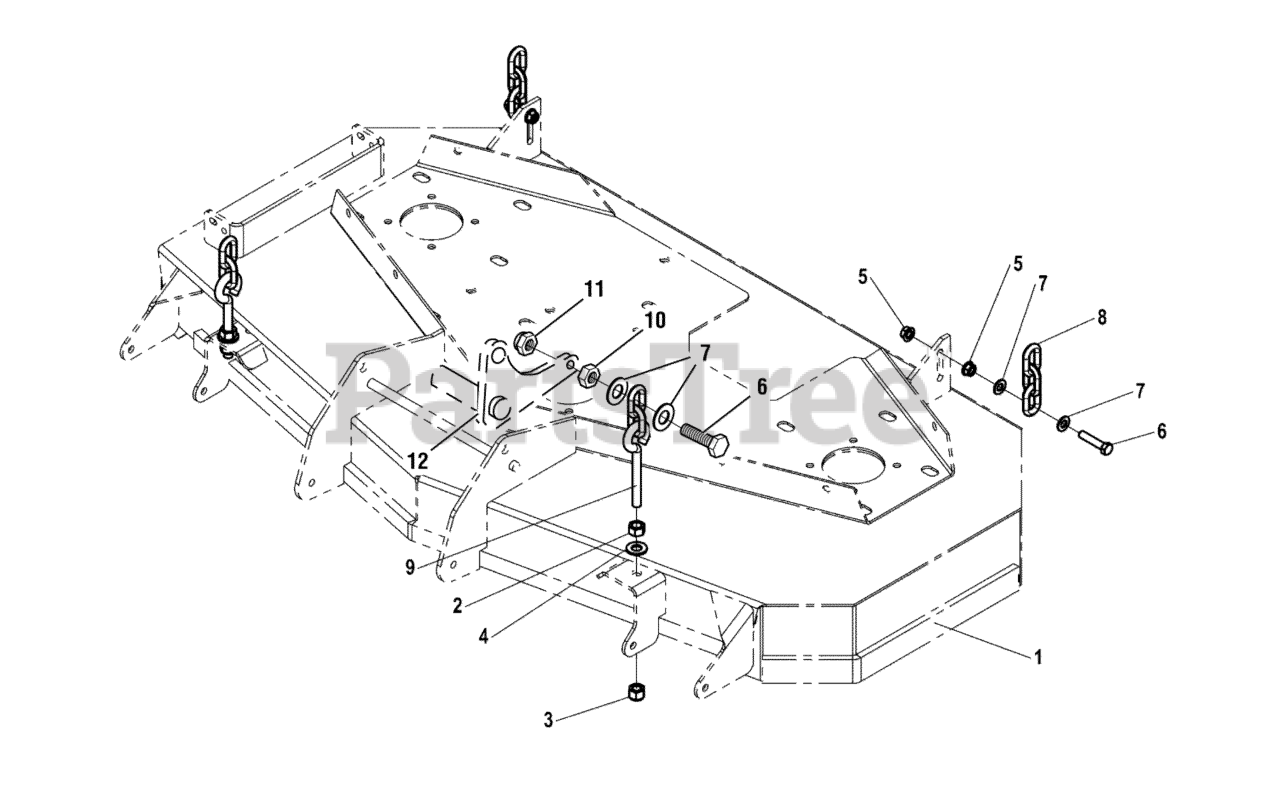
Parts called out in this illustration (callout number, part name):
1	MOWER DECK
2	NUT, 1/2-13 HEX
3	NUT, Hex Flange, Nylock, 1/2-13
4	WASHER, 1/2 SAE
5	NUT, 3/8-16 HEX SERRATED FLANGE
6	BOLT, 3/8-16 X 1-3/4" GD5 CZ
7	WASHER, 3/8 SAE
8	CHAIN, 5/16" GD30, 3 LINKS
9	HANGER, FRONT DECK-2LINK, 5.5" EB
10	NUT, 3/8-16 HEX JAM
11	NUT, 3/8-16 HEX NYLOCK FLANGE
12	DECK LIFT PIVOT
